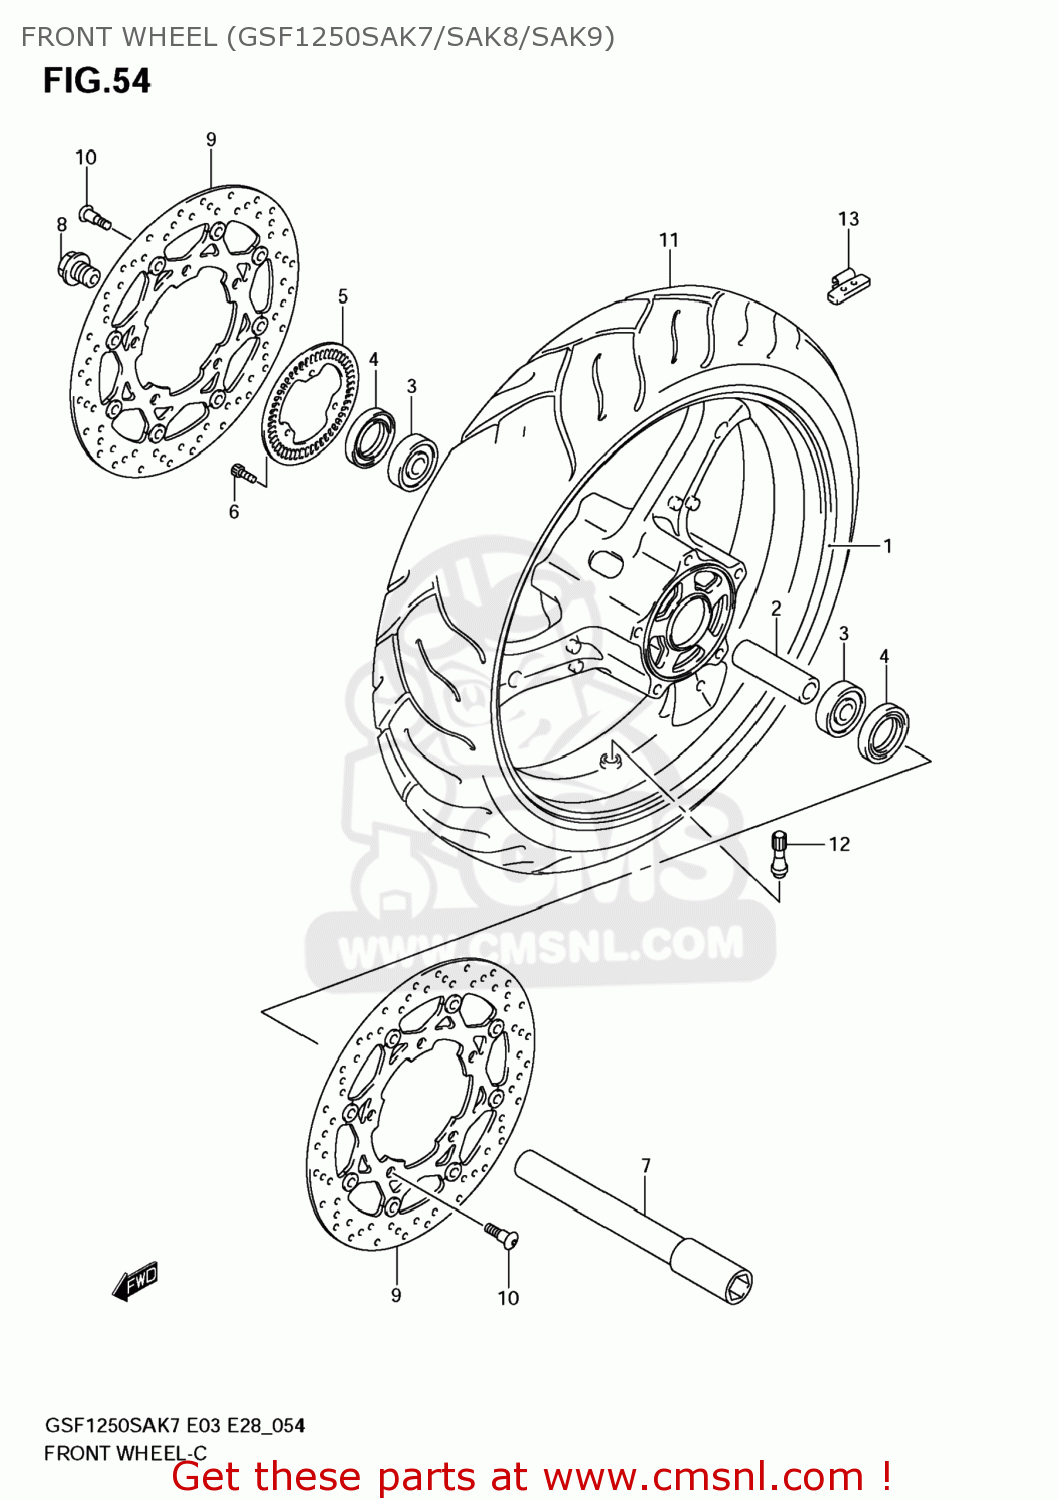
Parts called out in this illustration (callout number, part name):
1	WHEEL,FR(17M/CXMT3.50)
2	SPACER,FR HUB BEARING
3	BEARING(25X52X15)
4	SEAL,OIL(32X52X7)
5	RING,SPEED SENSOR FR(50T)
6	BOLT
7	AXLE,FR
8	BOLT,FRONT AXL
9	DISC,FRONT BRA
10	BOLT(8X21)
11	TIRE,FR
12	VALVE ASSY,WHEEL RIM(TR412)
13	BALANCER,WHEEL(10G)
